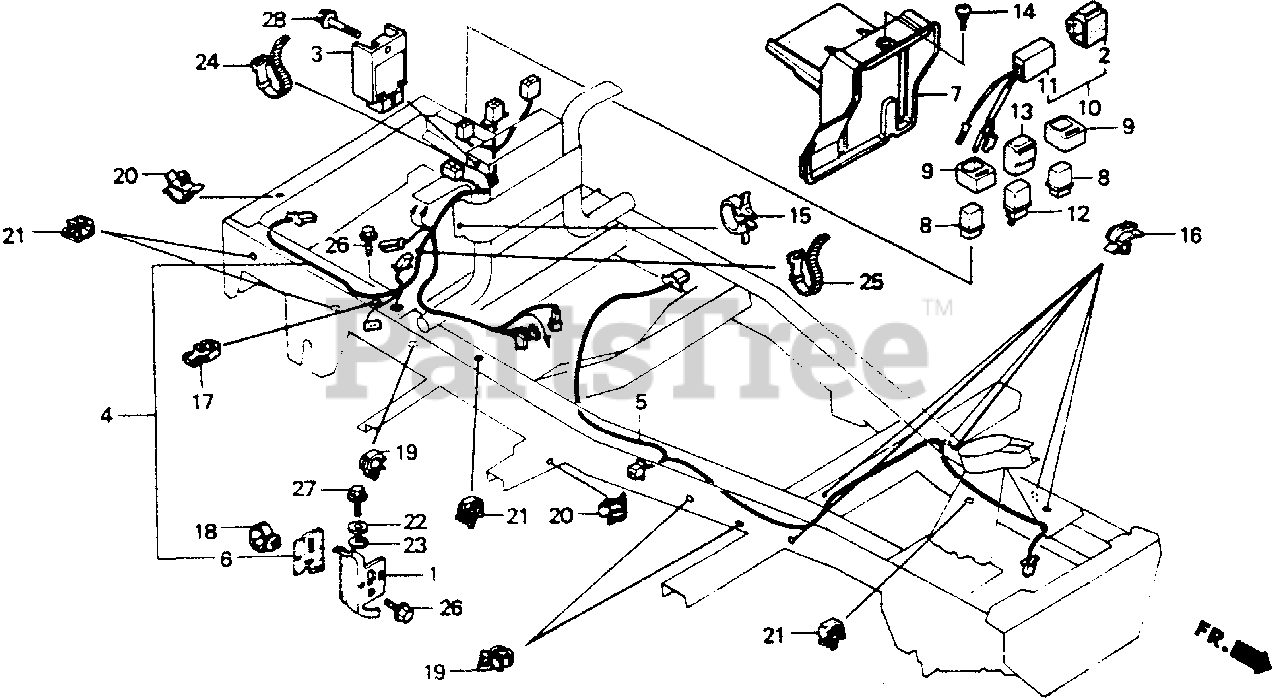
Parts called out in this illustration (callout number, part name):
1	STAY, CHANGE MOUNTING
2	RUBBER, IGNITION CONTROL MODULE
3	DIODE ASSY. (NOT AVAILABLE)
4	WIRE HARNESS ASSY., MAIN (NOT AVAILABLE)
5	SUB-WIRE HARNESS ASSY., FR.
6	HOLDER, CONNECTOR
7	COVER, ELECTRIC PARTS
8	RELAY ASSY., CONTROL (10A)
8	RELAY, CONTROL
9	SUSPENSION, CONTROL RELAY
10	CONTROL UNIT ASSY., BUZZER (NOT AVAILABLE)
11	CONTROL UNIT, BUZZER (NOT AVAILABLE)
12	RELAY, STARTER
12	RELAY, STARTER (TATEISHI)
13	SUSPENSION, STARTER RELAY (MITSUBA)
13	SUSPENSION, STARTER RELAY (TATEISHI)
14	SCREW, SPECIAL (6X8)
15	CLIP, HARNESS
16	CLIP, CORD
17	CLIP, HARNESS (5MM-15MM) (BLACK)
18	CLIP, WIRE HARNESS (25MM)
19	CLIP, HARNESS
20	CLIP, WIRE HARNESS
21	CLIP, HARNESS (7MM)
22	WASHER, PLAIN (6MM)
23	WASHER, SPRING (6MM)
24	BAND B1, WIRE
25	BAND B2, CABLE HARNESS
26	BOLT, FLANGE (6X10)
27	BOLT, FLANGE (6X12)
28	BOLT, FLANGE (6X18)
